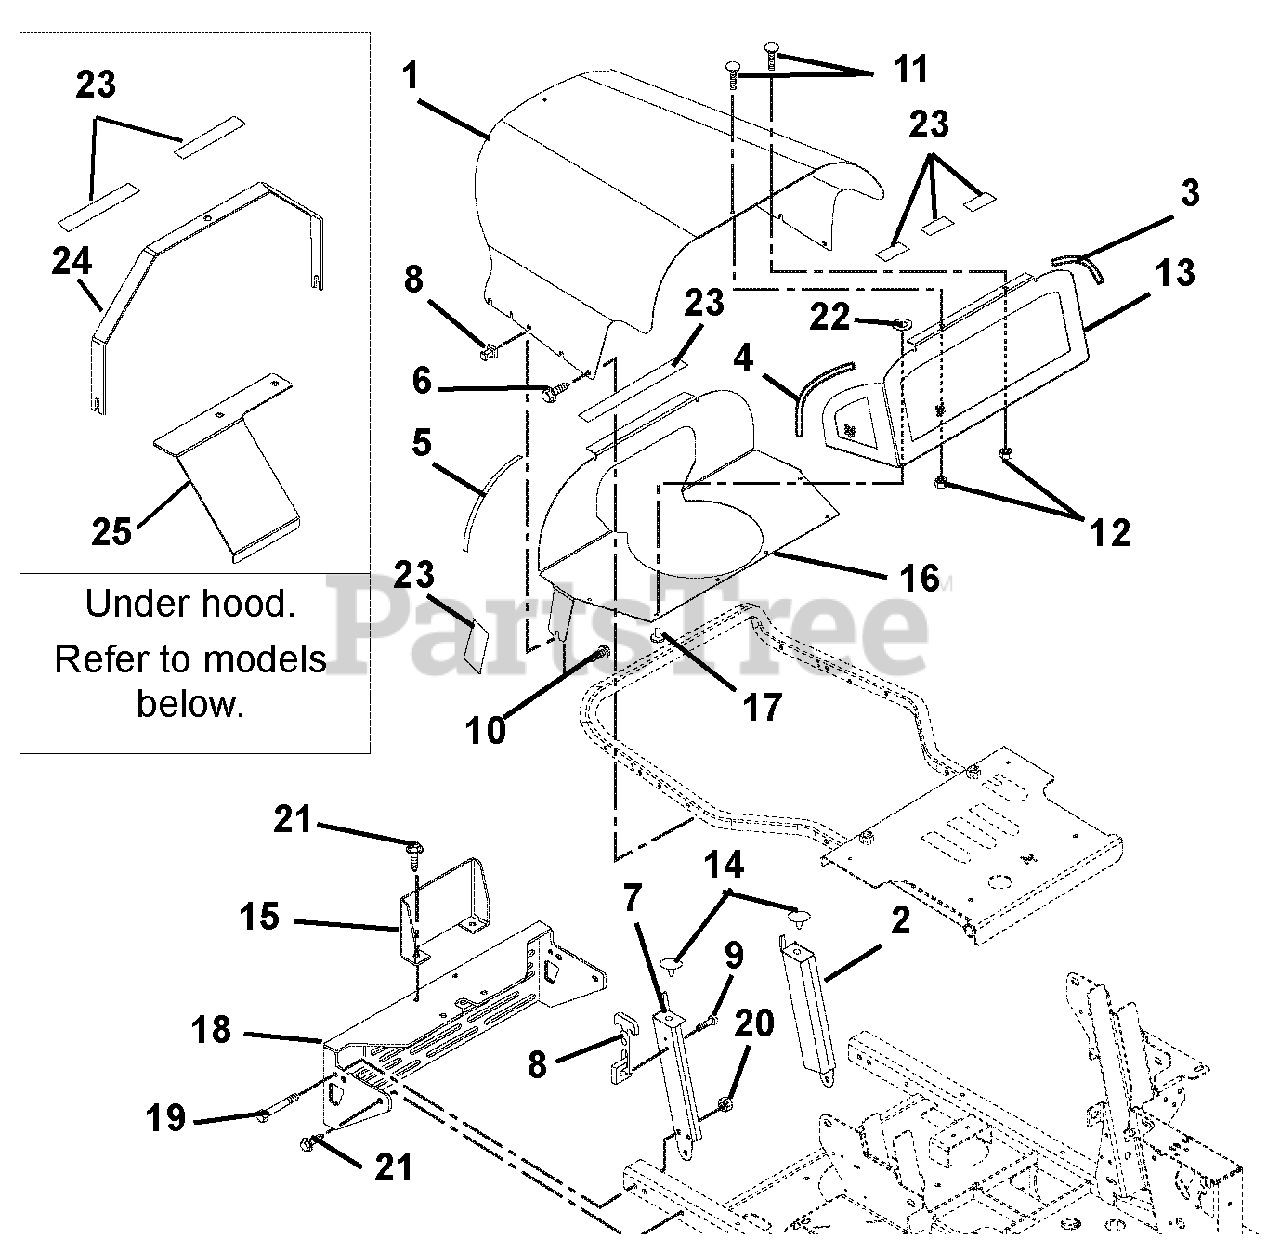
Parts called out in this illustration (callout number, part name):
2	Weldment, Hood Support, Left Hand
3	Seal, Trim Lok Bulk .06 Bubble (045, 046, 047, 052, 066, 067, 068, 071, 087, 088, 089, 091, 102, 107)
4	Seal, Trim Lok Bulk .06 Bubble (045, 046, 047, 052, 066, 067, 068, 071, 087, 088, 089, 091, 102, 107)
5	Seal, Trim Lok Bulk .06 Bubble (045, 046, 047, 052, 066, 067, 068, 071, 087, 088, 089, 091, 102, 107)
6	Screw, Tapping .38-16 x .50 Hex Washer Head
7	Weldment, Hood Support Right Hand
8	Latch, Rubber
9	Screw, Machine 10-24 x .50 Hex Washer Head
10	Screw, Machine 10-24 x 1.50 Hex Washer Head (045, 046, 047, 052, 066, 067, 068, 071, 087, 088, 089,
11	Bolt-Round Head Square Neck .25-20 x .50 Grade 5 (045, 046, 047, 052, 066, 067, 068, 071, 087, 088,
12	Nut-Locking-Top-Flange .25-20 (045, 046, 047, 052, 066, 067, 068, 071, 087, 088, 089, 091, 102, 107)
13	Weldment, Plenum (045, 046, 047, 052, 066, 067, 068, 071, 087, 088, 089, 091, 102, 107)
14	Button Bumper
15	Guard, Muffler
16	Support, Plenum (045, 046, 047, 052, 066, 067, 068, 071, 087, 088, 089, 091, 102, 107)
17	Rivet, Pop .18 x .402 (045, 046, 047, 052, 066, 067, 068, 071, 087, 088, 089, 091, 102, 107)
18	Bumper, Rear (045, 046, 047, 052, 066, 067, 068, 071, 087, 088, 089, 091, 102, 107)
19	Bolt, Hex .38-16 x 2.75 Grade 5
20	Nut-Locking-Top-Flange .38-16
21	Screw, Tapping .38-16 x .75 Hex Washer Head
22	Washer-Flat-Steel .219 x .50 x .049 (045, 046, 047, 052, 066, 067, 068, 071, 087, 088, 089, 091, 102, 107)
23	VHB Tape 4941F (045, 046, 047, 052, 066, 067, 068, 071, 087, 088, 089, 091, 102, 107)
24	Hood Support (045, 046, 047, 052, 066, 067, 068, 071, 087, 088, 089, 091, 102, 107)
25	Guard, Radiator Cap (084, 085, 086, 103, 104, 105, 106, 108)
